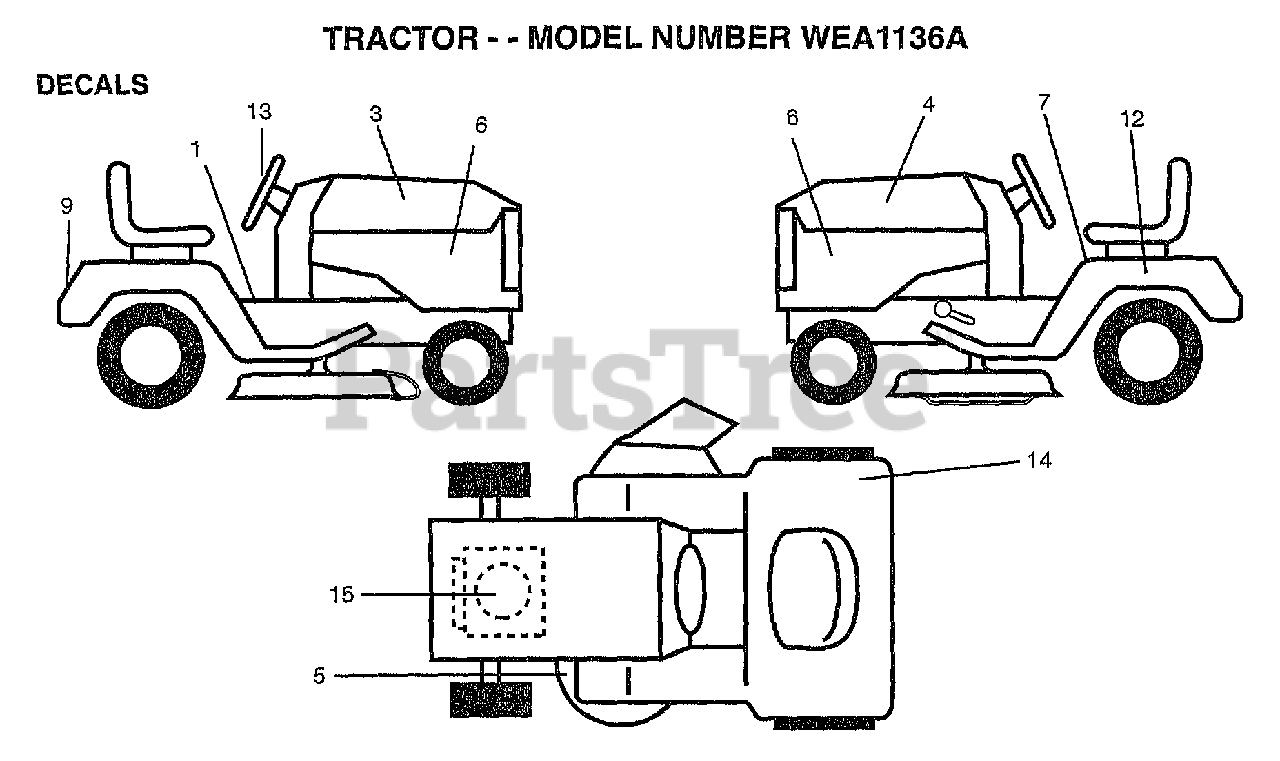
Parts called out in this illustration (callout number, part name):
1	"DECAL DANGER,FEND"
3	DECAL.HOOD.RH
4	DECAL.HOOD.LH
5	DECAL.V.BELT
6	DECAL.PNL.SIDE
7	DECAL.OPER.ENG.LR.GEAR
9	DECAL.FENDER.LOGO
12	DECAL.BATRY.3-3908
13	DECAL INSRT STEER
14	DECAL
15	DECAL.ENGINE
